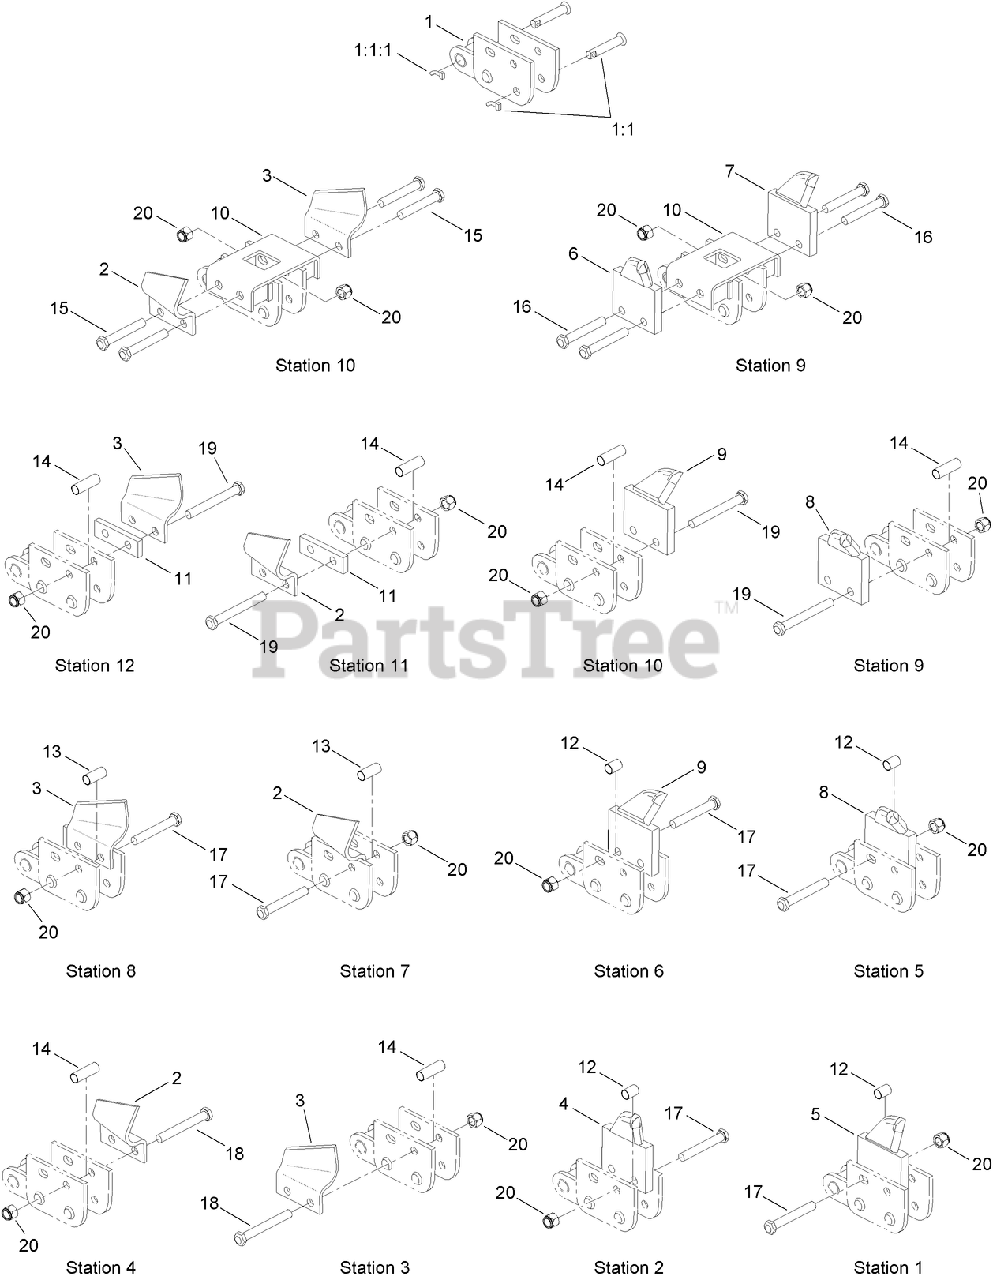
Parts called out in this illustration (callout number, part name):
1	CHAIN REPAIR LINK ASM
1:1	NOTCHED PIN AND KEEPER ASM
1:1:1	PIN-KEEPER
2	CUTTER-CUP, RH
3	CUTTER-CUP, LH
4	TOOTH-TERMINATOR, RH CENTER
5	TOOTH-TERMINATOR, LH CENTER
6	TOOTH-TERMINATOR, RH
7	TOOTH-TERMINATOR, LH
8	TOOTH-TERMINATOR, RH
9	TOOTH-TERMINATOR, LH
10	SADDLE-TOOTH SPREADER
11	SPACER-FLAT
12	SPACER-TUBE, INSIDE ADAPTER
13	SPACER-TUBE, INSIDE CUP
14	SPACER-TUBE, OUTSIDE MOUNT
15	BOLT-HH
16	BOLT-HH
17	BOLT-HH
18	BOLT-HH
19	BOLT-HH
20	NUT-LOCK
